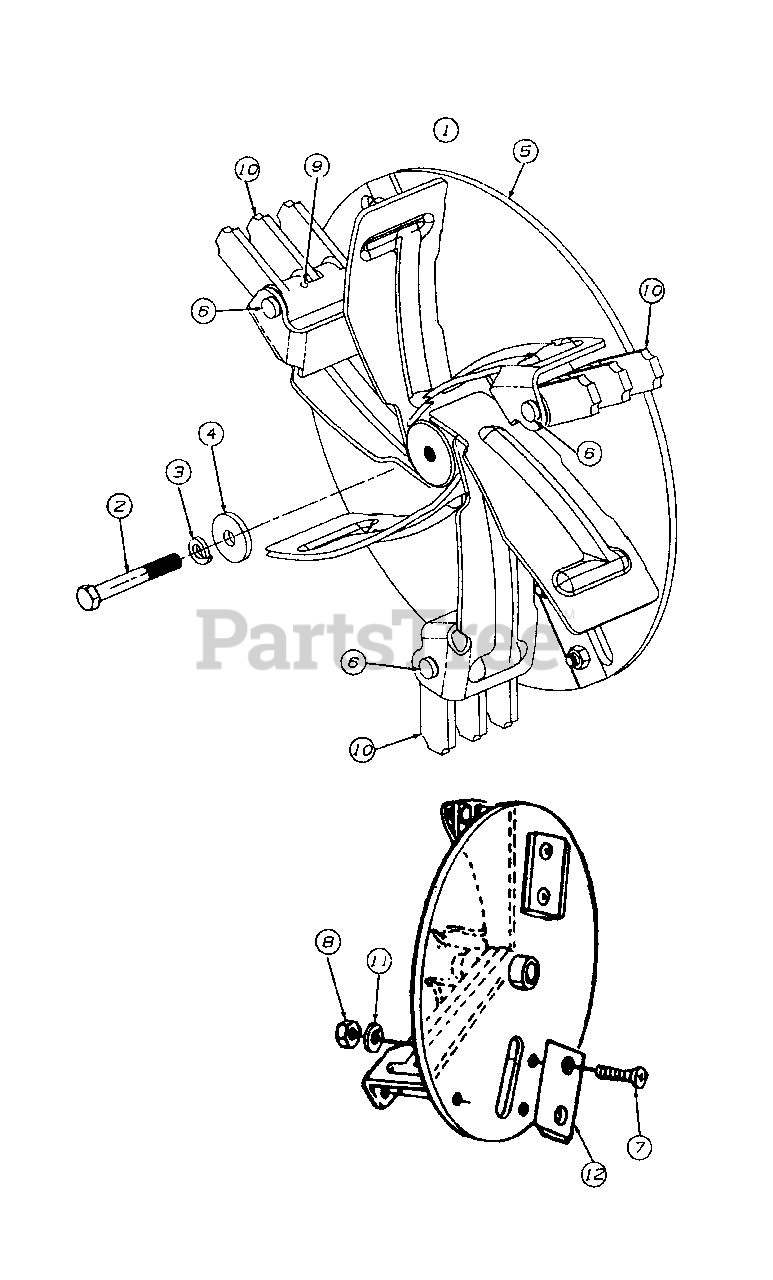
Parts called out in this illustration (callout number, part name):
1	IMPELLER ASS'Y COMP.
2	SCREW-HEX
3	WASHER-LOCK
4	WASHER-FLAT
5	IMPELLER ASSY
6	PIN-CLEVIS
7	SCREW-FLAT HEAD
8	NUT-HEX LOCK
9	PIN-ROLL SPRING
10	BLADE-FLAIL
11	WASHER-LOCK
12	BLADE-CHIPPER
